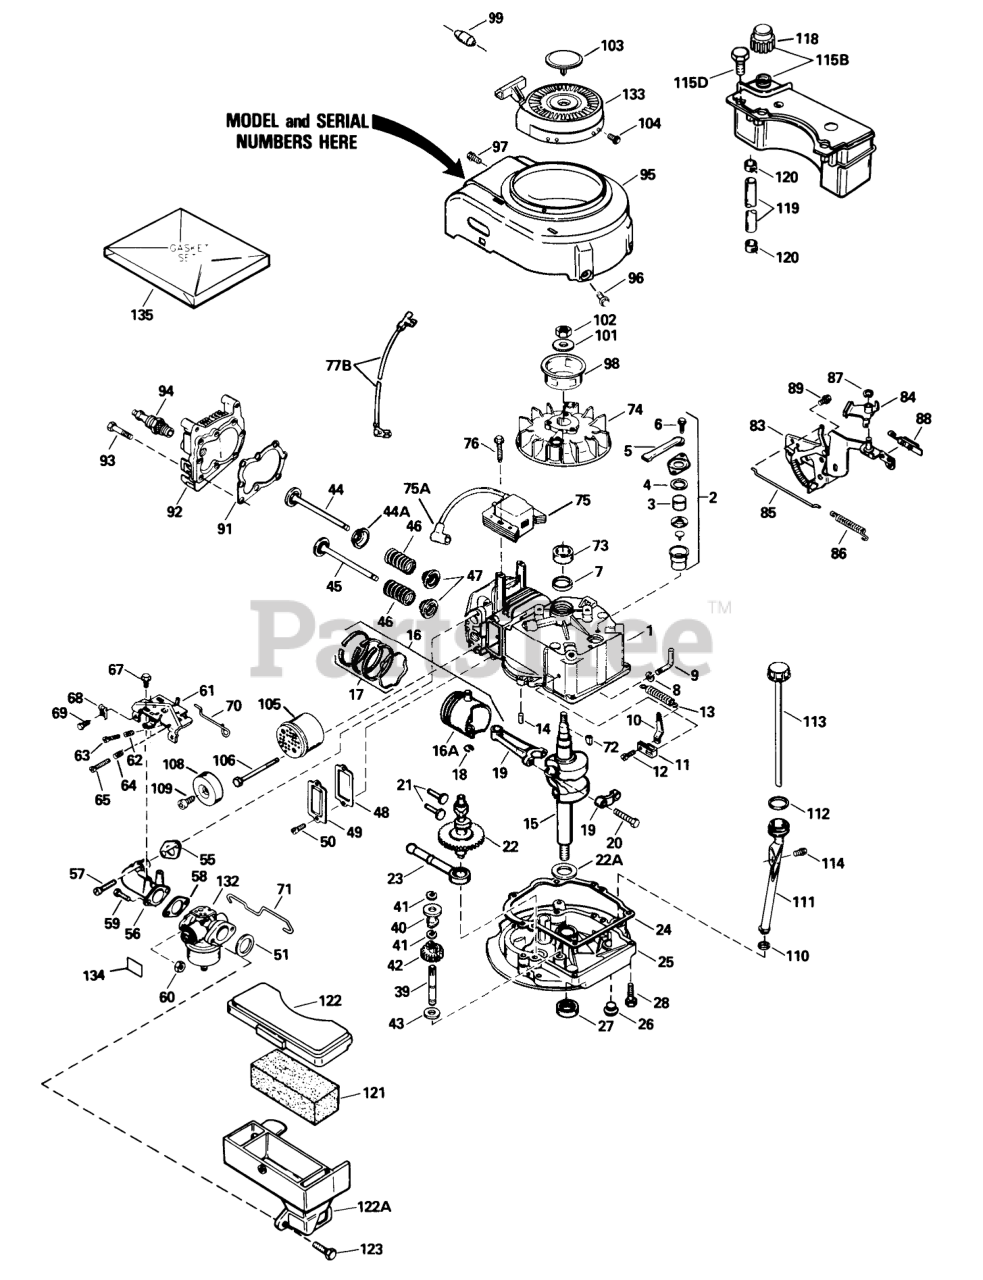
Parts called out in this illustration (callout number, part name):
1	Cylinder Assembly (Incl. Ref. #7 & 14)
2	Breather Assembly (Incl. Ref. #3-6)
3	Element-Breather
4	Gasket-Breather
5	Tube, Breaker
6	Screw (10-24 x 9/16)
7	Seal-Oil
8	Washer-Flat
9	Rod-Governor (Incl. Ref. #8)
10	Governor Lever
11	Clamp-Lever, Governor
12	Screw
13	Spring Governor
14	Pin-Dowel
15	Crankshaft
16	Piston-Pin & Ring Assy. (Std.) (Incl. Ref. #16A, 17 & 18)
16	Piston-Pin & Ring Assembly (.010 oversize) (Incl. Ref. #16A, 17 & 18)
16	Piston-Pin & Ring Assembly (.020 oversize) (Incl. Ref. #16A, 17 & 18)
16A	Piston & Pin Assembly (Std.) (Incl. Ref. #18)
16A	Piston & Pin Assembly (.010 oversize) (Incl. Ref. #18)
16A	Piston & Pin Assembly (.020 oversize) (Incl. Ref. #18)
17	Ring Set-Piston (Std.)
17	Ring Set, Piston(.0100versize)
17	Ring Set (.020" OS)
18	Ring-Retaining, Piston Pin
19	Rod Assembly-Connecting (Incl. Ref. #20)
20	Bolt-Rod, Connecting
21	Lifter-Valve
22	Camshaft(Mech.Comp. Release)
22A	Washer-Thrust
23	Oil Pump ASM
24	Gasket
25	Flange-Mounting (Incl. Ref. #26, 27 & 39)
26	Plug Oil Drain
27	Seal-Oil
28	Screw (1/4-20 x 1-1/4)
39	Shaft-Governor
40	Spool-Governor
41	Ring-Retaining
42	Gear Assembly-Governor (Incl. Ref. #43)
43	Washer
44	Valve-Intake (Std.) (Incl. Ref. #47)
44	Valve-Intake (1 /32" oversize) (Incl. Ref. #47)
44A	Seal Assy., Intake
45	Va Ive-Exha ust (Std.) (Incl. Ref. #47)
45	Va Ive-Exha ust (1 /32" oversize) (Incl. Ref. #47)
46	Spring-Valve
47	Cap-Valve, Spring
48	Gasket-Cover, Valve
49	Cover-Valve
51	Gasket-Cleaner, Air
55	Gasket-Intake Pipe
56	Pipe-Intake (Incl. Ref. #55)
57	Screw (1/4-20 x 1)
59	Screw (1/4-28 x 7/8)
60	Nut and Lock Washer (1/4-28)
61	Bracket Assembly-Control (Incl. Ref. #62-65)
62	61709/GIL1515A/95-5
63	Screw
64	Spring-Compression
65	Screw
67	Screw (10-24 x 9/16)
68	Conduit
69	Screw (10-32 x 3/8)
70	2035A67 ADD.ASSEMBL
71	Link-Throttle
72	Key-Flywheel
74	Flywheel
75	Solid State
75A	Cover-Spark Plug
76	Screw
77B	Ground Wire
83	Bracket-S.E. Brake
84	Lever-Brake
85	Link-Control
86	Spring-Extension
87	Ring-Retaining
88	Terminal
89	Screw (1/4-20 x 3/8)
91	Gasket-Cylinder Head
92	Head-Cylinder
93	Screw (5/16-18x1-1/2)
94	Spark Plug-Resistor (R J19 L M)
95	Housing-Blower
96	Screw (1/4-20 x 1/2)
97	Screw (10-24 x 9/16)
98	Hub-Starter
99	Retainer-Starter Rope
101	Washer-Belleville
102	Nut-Flywheel
103	Plug Starter
104	Screw, Hex Hd.
105	Muffler Assembly (Incl. Ref. #106)
108	Cover-Muffler
109	Screw (8-32 x 3/8)
111	Oil Fill Tube
113	Dipstick
114	Screw (10-32 x 1/2)
115B	Tank Assembly (Incl. Ref. #118 & 126)
115D	Screw (10-32 x 35/64)
118	Cap-Fuel
119	Line-Fuel
120	Clamp-Line, Fuel
121	Filter-Air Cleaner
122	Cover Air Cleaner
122A	Body Air cleaner
132	Carburetor (Incl. Ref. #58)
133	Starter-Rewind
134	Decal-Primer
135	Gasket Set (Incl. Items Marked )
